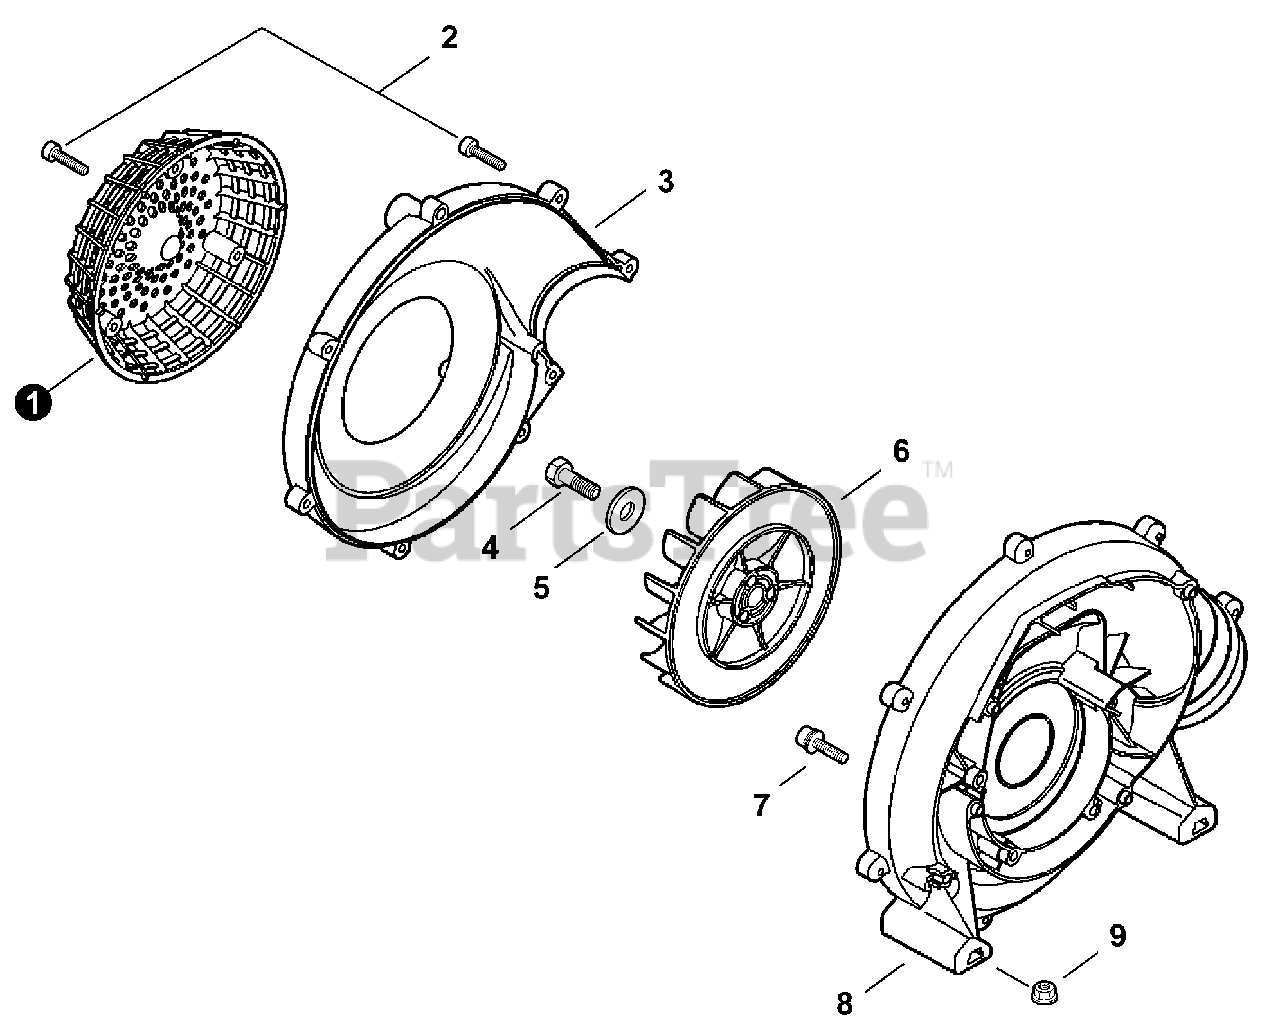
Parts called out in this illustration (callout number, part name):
1	GUARD, DEBRIS
2	SCREW TAPPING 5×20
3	COVER, FAN
4	BOLT 8×14
5	WASHER 8.2×31×0.8
7	BOLT 4×20
8	CASE, FAN
9	NUT, FLANGE 5
